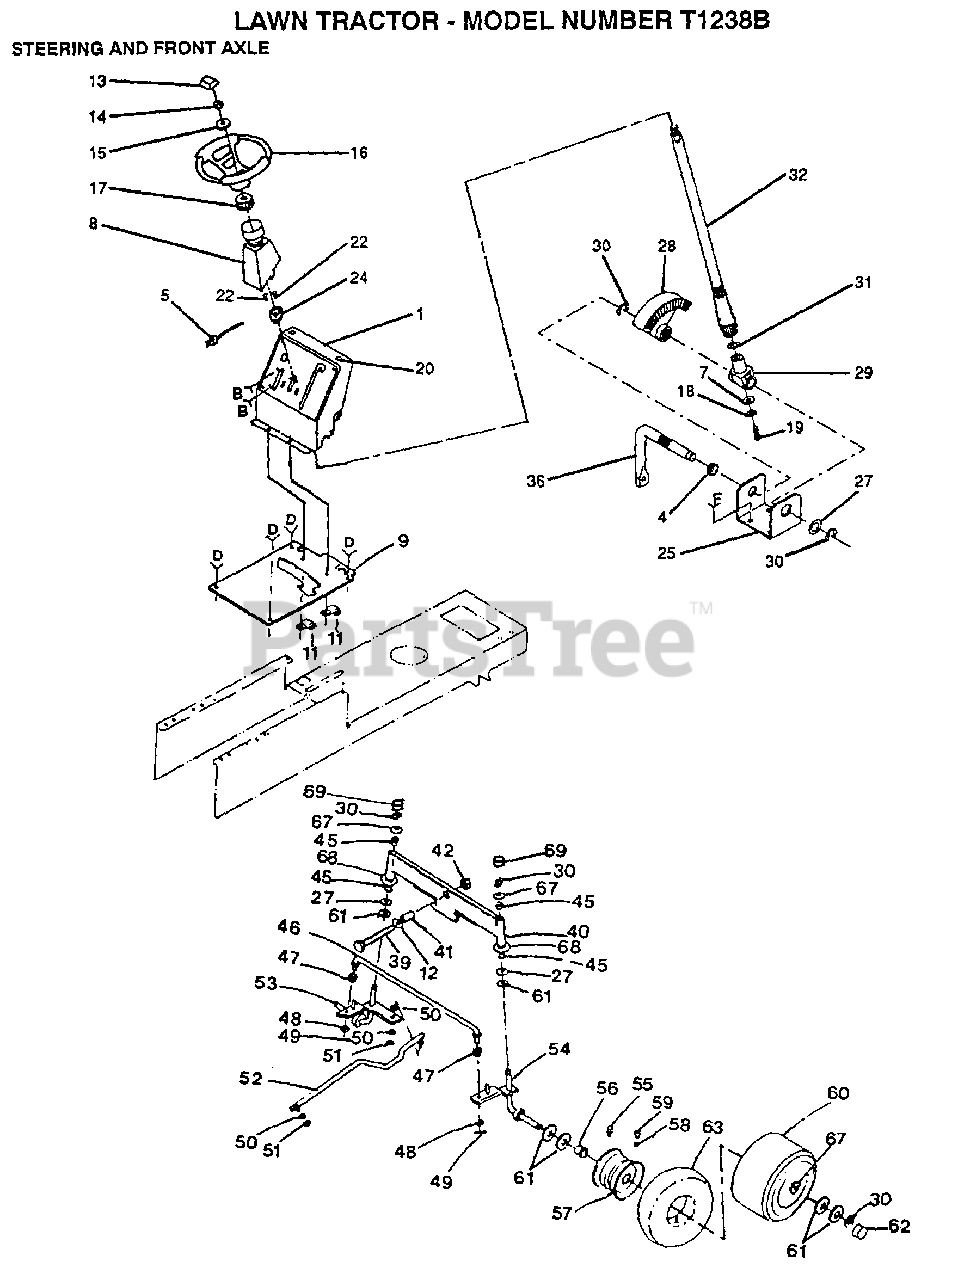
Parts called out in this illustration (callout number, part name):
4	NYLINER T
8	"TUBE, STR SHAFT"
11	CLIP T
13	INSERT-WHEEL LT
15	WASHER
17	ADAPTER LT
18	LOCKWASHER
19	"SCREW,SPECIAL"
24	"BUSHING,STEERING"
25	"BRKT,STEERING"
27	WASHER .T
29	SUPPORT.SHAFT
30	RING
31	THRUST WASHER
32	SHAFT WELD STR T
39	BOLT LT
41	BEARING
45	COL. SRTG. BEAR.
48	WASHER
49	COTTER PIN
50	LOCKWASHER
53	SPINDLE-LH LT
55	FITTING LT
56	"FLANGE, BEARING"
58	VALVE CAP
59	VALVE STEM LT
61	WASHER
62	HUB CAP
63	TUBE.5.3/4.5/6
67	WASHER
68	WASHER
69	CAP
